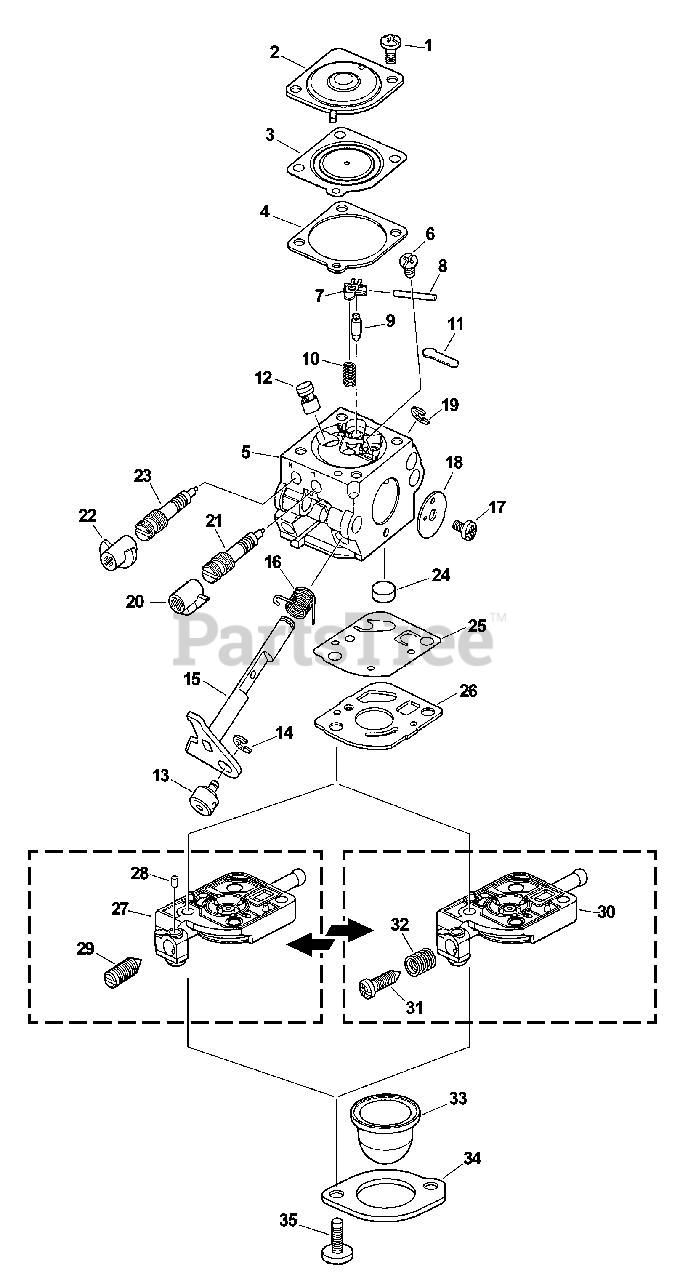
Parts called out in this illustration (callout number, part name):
2	COVER, METERING
3	DIAPHRAGM, METERING
4	GASKET, METERING
5	BODY, CARBURETOR
6	SCREW, METERING LEVER PIN
7	LEVER, METERING
8	PIN, METERING LEVER
9	VALVE, INLET NEEDLE
10	SPRING, METERING LEVER
11	PLUG, WELCH
12	NOZZLE, CHECK VALVE
14	RING, RETAINING
15	SHAFT, THROTTLE
16	SPRING, RETURN
18	VALVE, THROTTLE
19	RING, RETAINING
20	CAP, LIMITER
21	NEEDLE - LOW SPEED
22	CAP, LIMITER
23	NEEDLE - HIGH SPEED
24	STRAINER
25	DIAPHRAGM, PURGE
26	GASKET, PURGE
27	BASE, PURGE
28	PIECE, FRICTION
29	SCREW, IDLE ADJUST
30	BASE, PURGE
31	SCREW, IDLE ADJUST
32	SPRING, IDLE ADJUST
33	BULB, PURGE
34	RETAINER, PURGE BULB
35	SCREW, RETAINER
